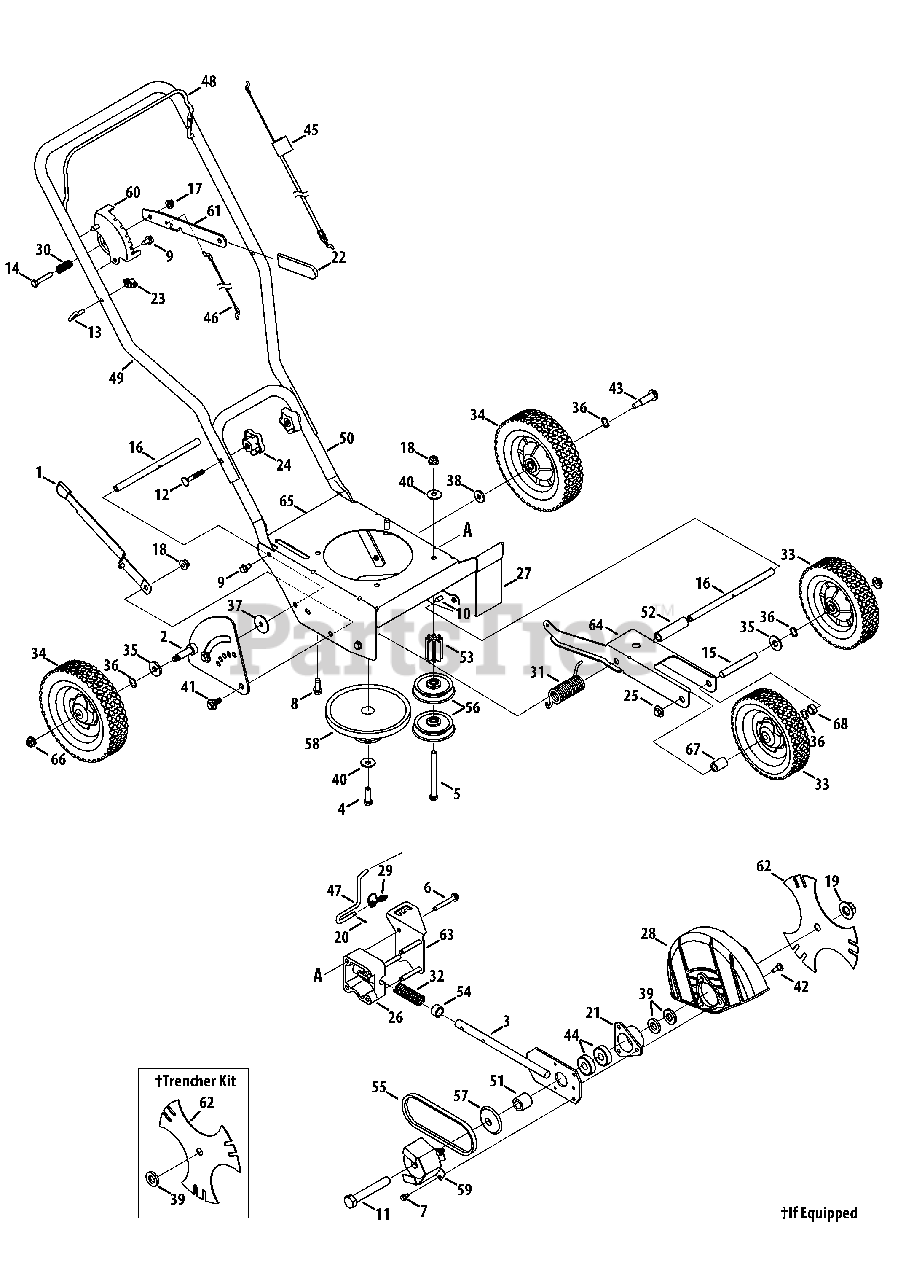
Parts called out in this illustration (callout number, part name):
1	Curb Height Adjustment Lever
2	Curb Height Adjuster Plate
3	Blade Plate Assembly
4	Screw 3/8-24
5	Screw 3/8-16
6	Hex Screw, 5/16-18
7	Self-tapping Screw, 1/4-20
8	Screw, 3/8-16
9	Hex Screw, 5/16-12
10	Hex Screw 5/16-18
11	Hex Screw, 5/8-18
12	Carriage Bolt, 5/16-18
13	Rope Guide (Eye Bolt)
14	Hex Screw, 5/16-18
15	Axle Shaft .50x6.65
16	Frame Spacer .50x9.25
17	Lock Flange Nut, 5/16-18
18	Flange Nut 3/8-16
19	Flange Nut, 5/8-18
20	Clevis Pin 3/32 x .625
21	Bearing Cup
25	Push Cap 1/2" rod
26	Bearing Block
27	Debris Guard
28	Blade Guard
29	Double Torsion Spring
30	Compression Spring
31	Torsion Spring
32	Compression Spring
33	Wheel 7 x 1.75 T-Tread
34	Wheel 8 x 1.75 T-Tread
35	Flat Washer, .531 x 1.25 x .181
36	Wave Washer .531 x .781 x .013
37	Flat Washer, .385 x 1.5 x .075
38	Flat Washer .385 x 1.0 x .135 †
39	Flat Washer .635x1.24x.181
40	Bell Washer,.396 x 1.140
41	Shoulder Screw, 3/8-16
42	Shoulder Screw
43	Shoulder Screw, 3/8-16
44	Bearing, .625 ID x 1.57 OD
45	Control Cable (Briggs & Stratton)
46	Wheel Adjustment Cable
47	Blade Adjustment Rod
48	Bail Handle
49	Upper Handle
50	Lower Handle
51	Spacer, .63 x 1.12 x 1.06
53	Pulley Mount Spacer
54	Spacer, .64 x.88 x .50
56	Flat Idler Pulley, 2.5 OD
58	Combination Flywheel Pulley
61	Depth Index Lever
62	Tri-Star Blade
63	Bracket Plate
64	Dual Wheel Bracket
65	Frame
66	Flange Lock Nut, 3/8-16
67	Spacer., .525 x .775 x .93
68	Spacer., .505ID x .88OD x .440
